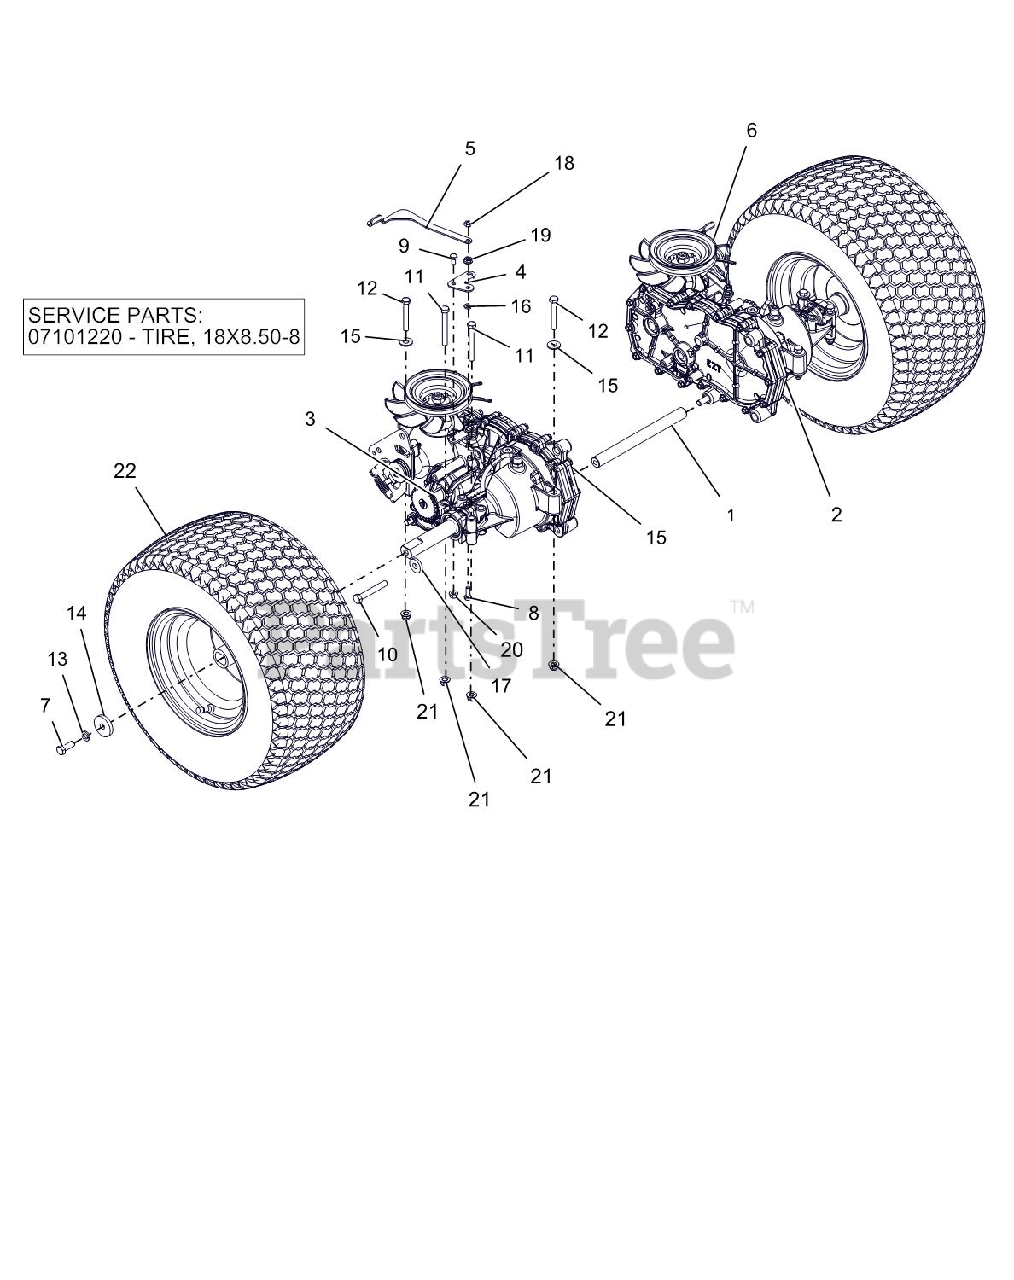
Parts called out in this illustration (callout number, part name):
1	ROD, TRANSAXLE BRACE
2	TRANSAXLE,LH EZT D-SHFT SHORT
3	TRANSAXLE,RH EZT D-SHFT SHORT
4	BRKT, DUMP VALVE EXTENSION
5	BRKT, DUMP VALVE RH
6	BRKT, DUMP VALVE LH
7	BLT-HEX .38-16X1.0 GR8 YZ EP30
8	@BLT-HEX .25-20X.75 GR5 YWZC
9	@BLT-HEX .25-20X.50 GR5 YWZC
10	@BLT-HEX .38-16X2.50 GR5 YWZC
11	@BLT-HEX .31-18X2.75 GR5 YWZC
12	@BLT-HEX .31-18X2.25 GR5 YWZC
13	@WSHR-LK .38X.094 REG YWZC
14	WSHR,FLT STL.406X1.50X.245YWZC
15	@WSHR-FL-STL.38X.875X.083 YWZC
16	WSHR-FL-STL .265X.50X.087YWZC
17	WSHR-FL-STL .406X1.00X.188 YWZ
18	NUT-LK-CTR JAM .25-20 YWZC
19	@NUT-SPNLK-FLG .25-20 YWZC
20	@NUT-LK-TOP-FLG .25-20 YWZC
21	@NUT-LK-NYL-FLG .31-18 YWZC
22	ASM, WHL/TIRE 18X8.50-8 DHUB
22	TIRE, 18X8.50-8
22	TUBE 18X9.50-8
